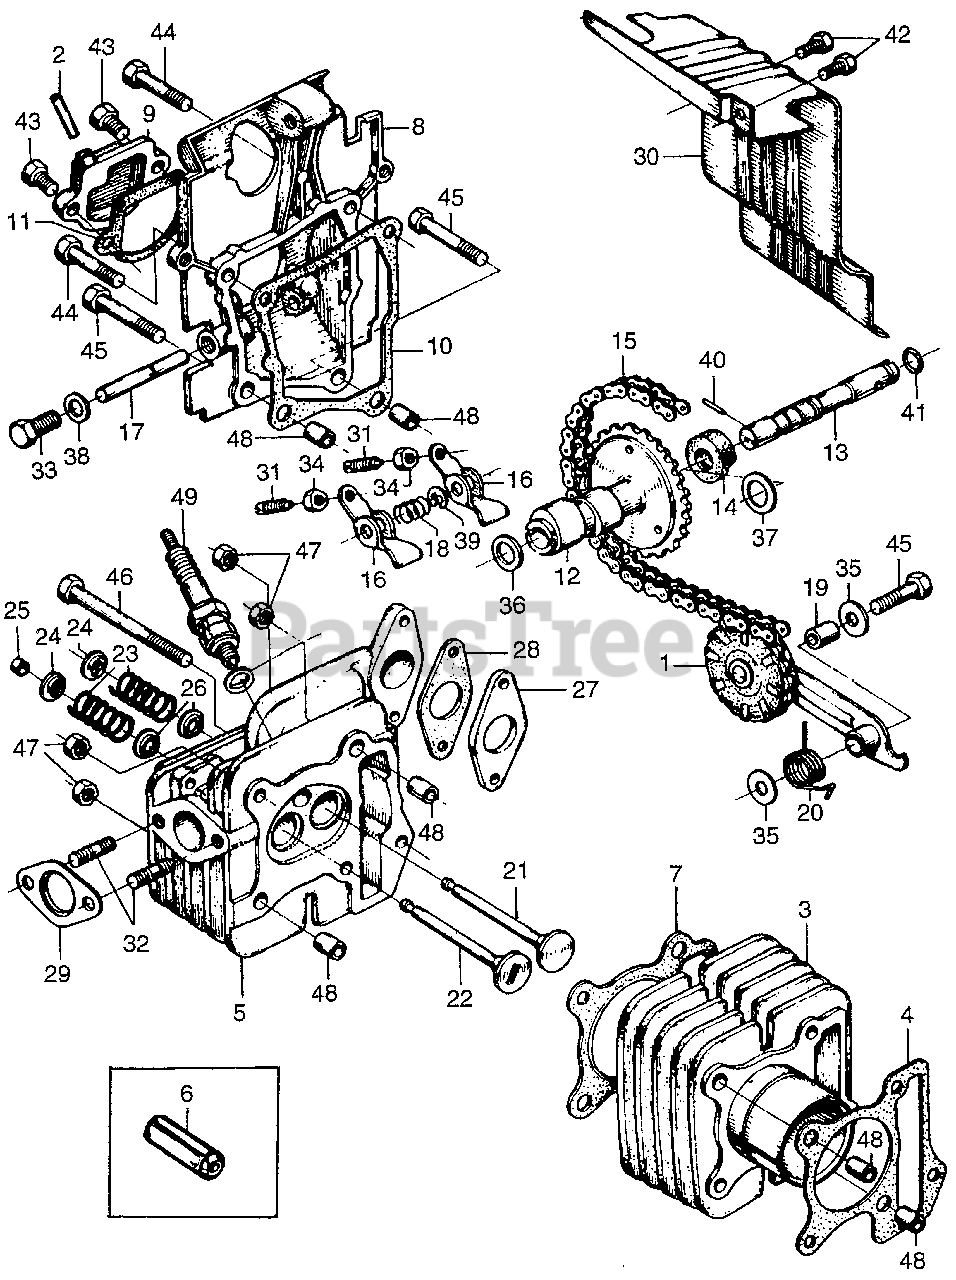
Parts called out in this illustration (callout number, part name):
1	TENSIONER, CAM CHAIN (NOT AVAILABLE)
2	JOINT, BREATHER (NOT AVAILABLE)
4	GASKET, CYLINDER (NOT AVAILABLE)
5	CYLINDER HEAD
6	GUIDE, VALVE
7	GASKET, CYLINDER HEAD
8	COVER, CYLINDER HEAD
9	CAP, TAPPET (NOT AVAILABLE)
10	GASKET, CYLINDER HEAD COVER
11	GASKET, CAP (NOT AVAILABLE)
13	PIN, CAMSHAFT CENTER (NOT AVAILABLE)
14	COLLAR, CAMSHAFT (NOT AVAILABLE)
15	CHAIN, CAM
16	ARM, VALVE ROCKER (NOT AVAILABLE)
17	SHAFT, VALVE ROCKER ARM (NOT AVAILABLE)
18	SPRING, ROCKER ARM SIDE (NOT AVAILABLE)
19	COLLAR, TENSIONER
20	SPRING, CAM CHAIN TENSIONER (NOT AVAILABLE)
21	VALVE, IN.
22	VALVE, EX.
23	SPRING, VALVE (NOT AVAILABLE)
24	RETAINER, VALVE SPRING
25	ADJUSTER, TAPPET CLEARANCE (NOT AVAILABLE)
26	SEAT, VALVE SPRING (LOWER) (NOT AVAILABLE)
27	INSULATOR, CARBURETOR (NOT AVAILABLE)
28	GASKET, CARBURETOR INSULATOR
29	GASKET, EX. PIPE (NOT AVAILABLE)
30	VANE, GUIDE
31	SCREW, TAPPET ADJ. (NOT AVAILABLE)
32	BOLT STUD (6X23) (NOT AVAILABLE)
33	BOLT, SEALING (8MM) (NOT AVAILABLE)
34	NUT, TAPPET ADJ.
35	WASHER, SHIFT DRUM SIDE (NOT AVAILABLE)
36	WASHER A (10MM) (NOT AVAILABLE)
37	WASHER B (10MM) (NOT AVAILABLE)
38	GASKET, OIL PIPE JOINT
39	CIRCLIP (6MM)
40	PIN, KNOCK (3X12)
41	O-RING (6.9X1.5)
42	BOLT, HEX. (5X8)
43	BOLT, HEX. (6X16)
44	BOLT, HEX. (6X25)
45	BOLT, HEX. (6X35)
46	BOLT, HEX. (6X71) (NOT AVAILABLE)
47	NUT, HEX. (6MM)
48	PIN A, DOWEL (8X14)
49	SPARK PLUG (C6HSA) (NGK)
